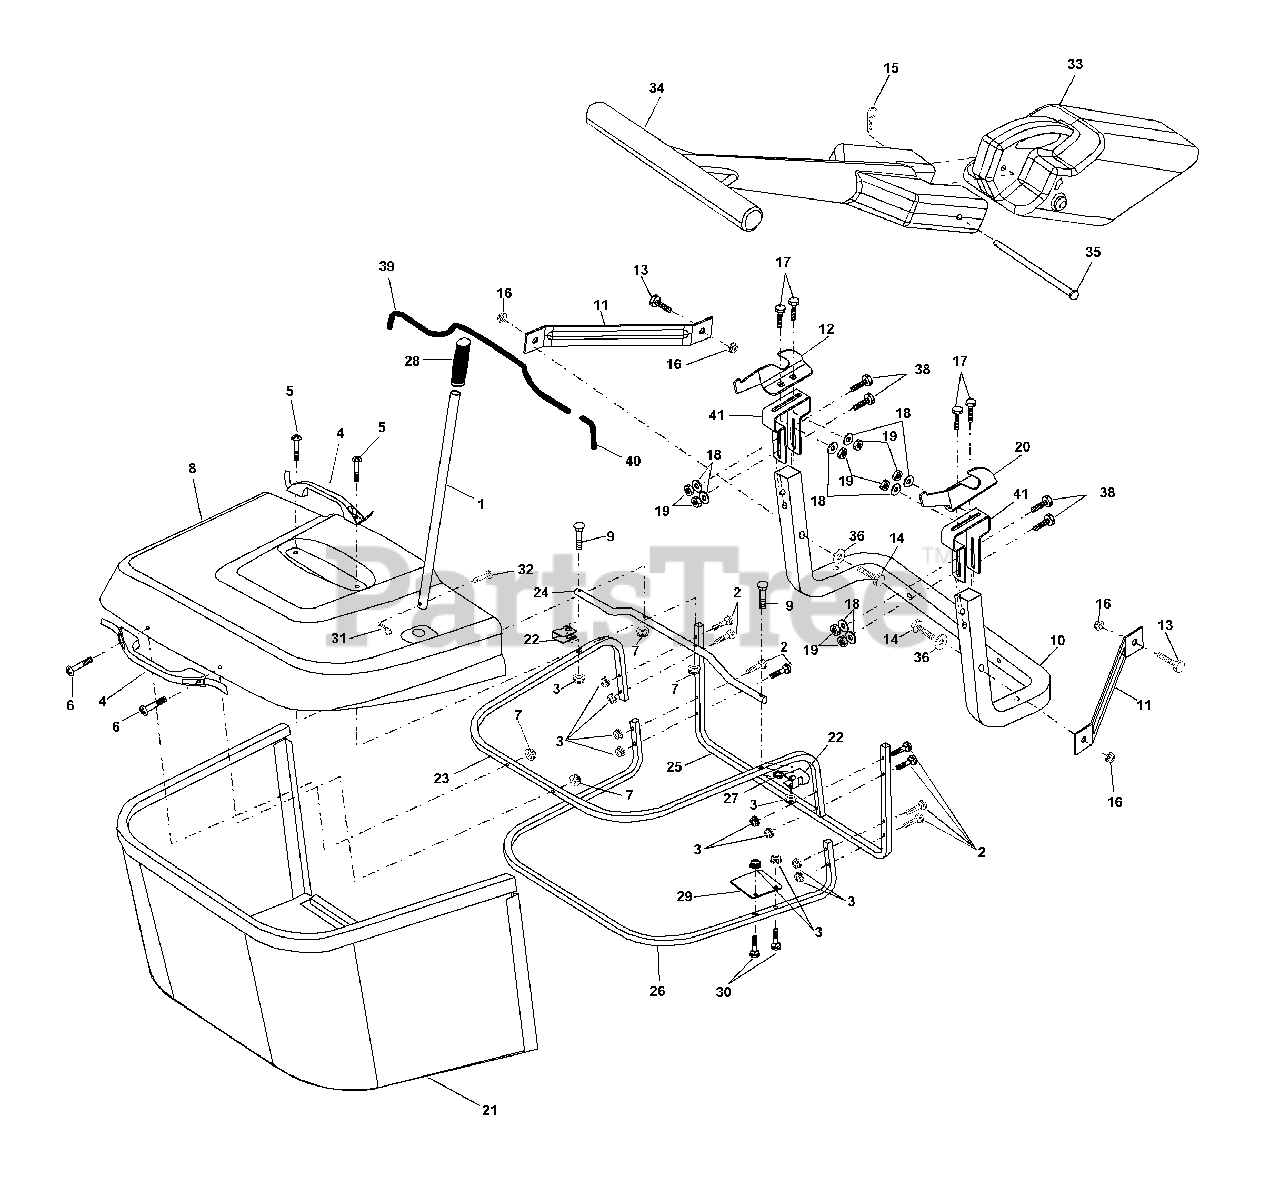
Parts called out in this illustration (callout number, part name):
1	Tube Handle Bagger CRD
2	Bolt Carriage 1/4-20 x 2.0 Gr.5
3	Nut Lock 1/4 Lge Flg Gr. 5 Zinc
4	Handle Bagger w/Lvrs Blk CRD
5	Screw Pan Head #10-24 x 1.50 Blk
6	Screw Pan Hd
7	Nut Wiz Lock Hex Serr/Hd 10-24
8	Cover Bagger Plastic CRD MS422
9	Bolt Carriage 1/4-20 x 2.25d x Gr.5
10	Tube Support Bagger CRD
11	Bracket Support Upper Bag CRD
12	Bracket Pnt Adj Bagger Lh CRD
13	Bolt Rdhd Sht Sqnk 3/8-16 x 3/4
14	Bolt Hex 3/8-16 x 2-1/2 Gr.5
15	Retainer Spring
16	Nut Lock Flg 3/8-16 Unc
17	Bolt Rdhd Sht Sqnk 5/16 -18 Unc x 3/4
18	Washer 11/32 x 3/4 x 16 Ga.
19	Nut Crown Lock 5/16-18 Unc Blk
20	Bracket Pnt Adj Bagger Rh CRD
21	Bag Asm CRD
22	Bracket Side Bagger CRD
23	Tube Upper Bagger CRD
24	Tube Pivot Bagger CRD
25	Tube Front Bagger CRD
26	Tube Lower Bagger CRD
27	Bushing Snap Bagger CRD
28	Grip Handle Black
29	Plate Stop Bagger handle CRD
30	Bolt Carriage 1/4-20 x 1-1/4 Gr.5
31	Retainer Spring 1" Zinc/Cad
32	Rivet Rd Hd Drilled 3/8 Dia
33	Plug Mulcher
34	Handle Mulcher
35	Pin Mulcher
36	Washer 13/32 x 1-1/4 x 16 Ga.
38	Bolt 5/16-18 x 2-1/2
39	Trim, Long
40	Trim, Short
41	Bracket Pnt Adj Pvt Bagger CRD
